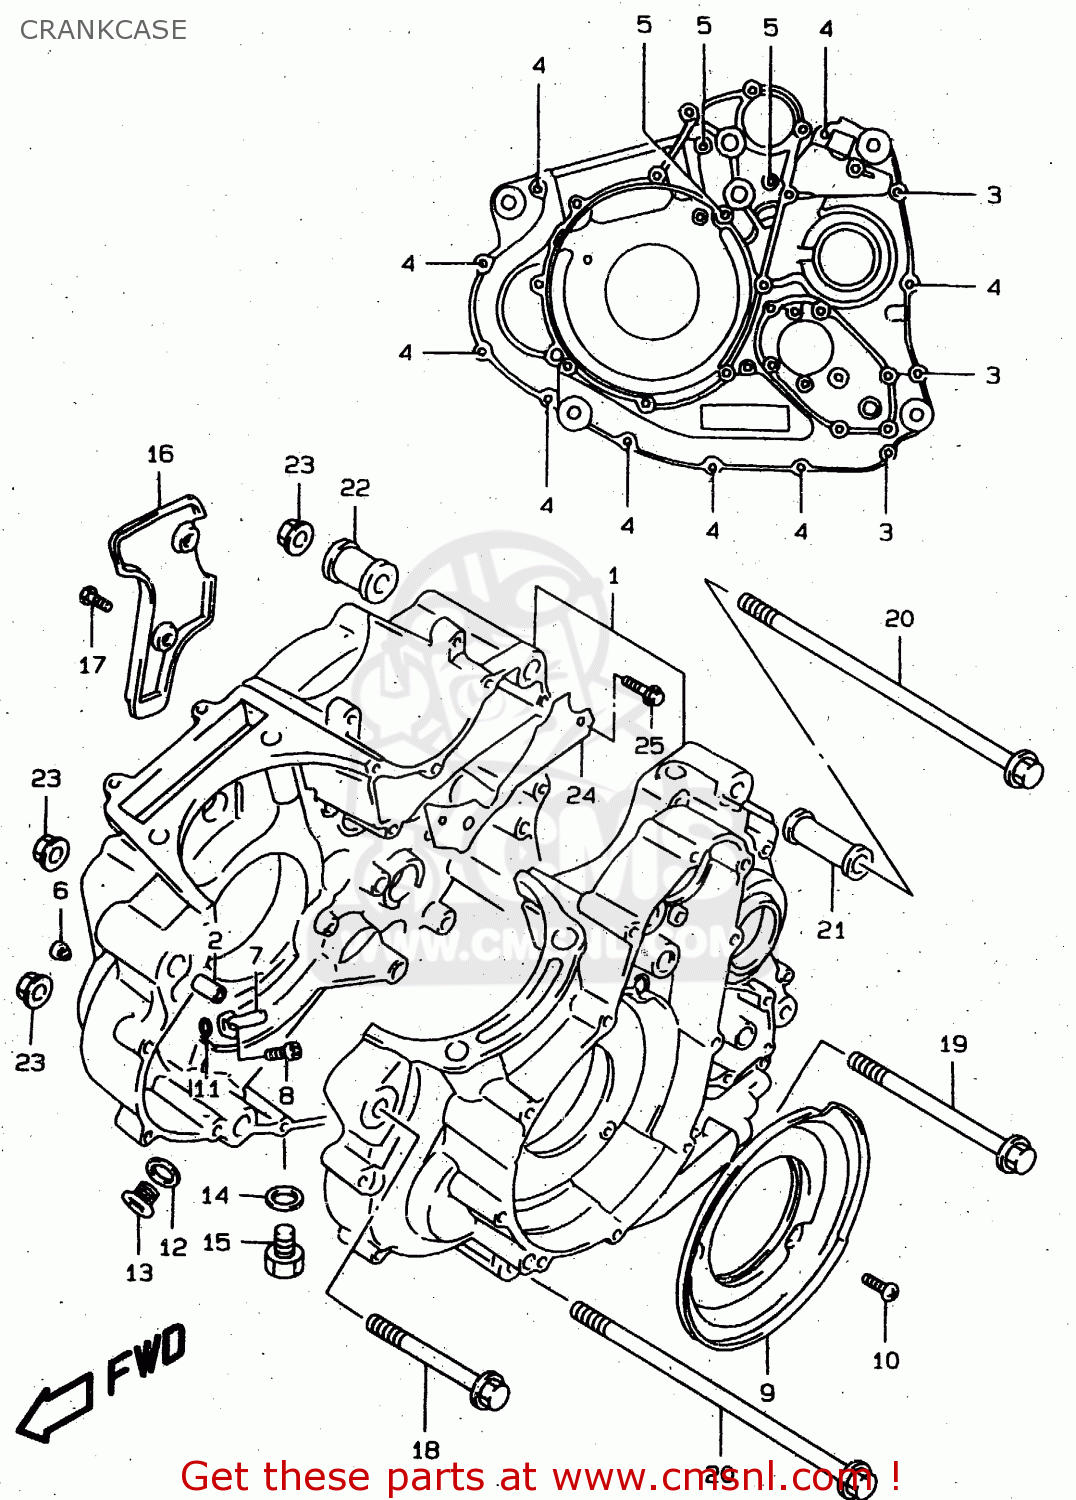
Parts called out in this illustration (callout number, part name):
1	CRANKCASE SET
2	PIN
3	BOLT
4	BOLT
5	BOLT
6	JET,OIL GALLERY
7	JET,PISTON COOLING
8	BOLT(6X12)
9	SEPARATOR,CRANKCASE OIL
10	SCREW
11	O RING(D:1.2,ID:4)
12	GASKET(13.8X18.8X4.8) (NAS)
13	PLUG,14X12
14	GASKET(13.8X18.8X4.8) (NAS)
15	PLUG
16	COVER,BREATHER
17	SCREW
18	BOLT(10X100)
19	BOLT(10X130)
20	BOLT(10X235)
21	SPACER,ENGINE MOUNT(L:65)
22	SPACER,ENGINE MOUNT(L27)
23	NUT
24	PLATE,BREATHER
25	BOLT
